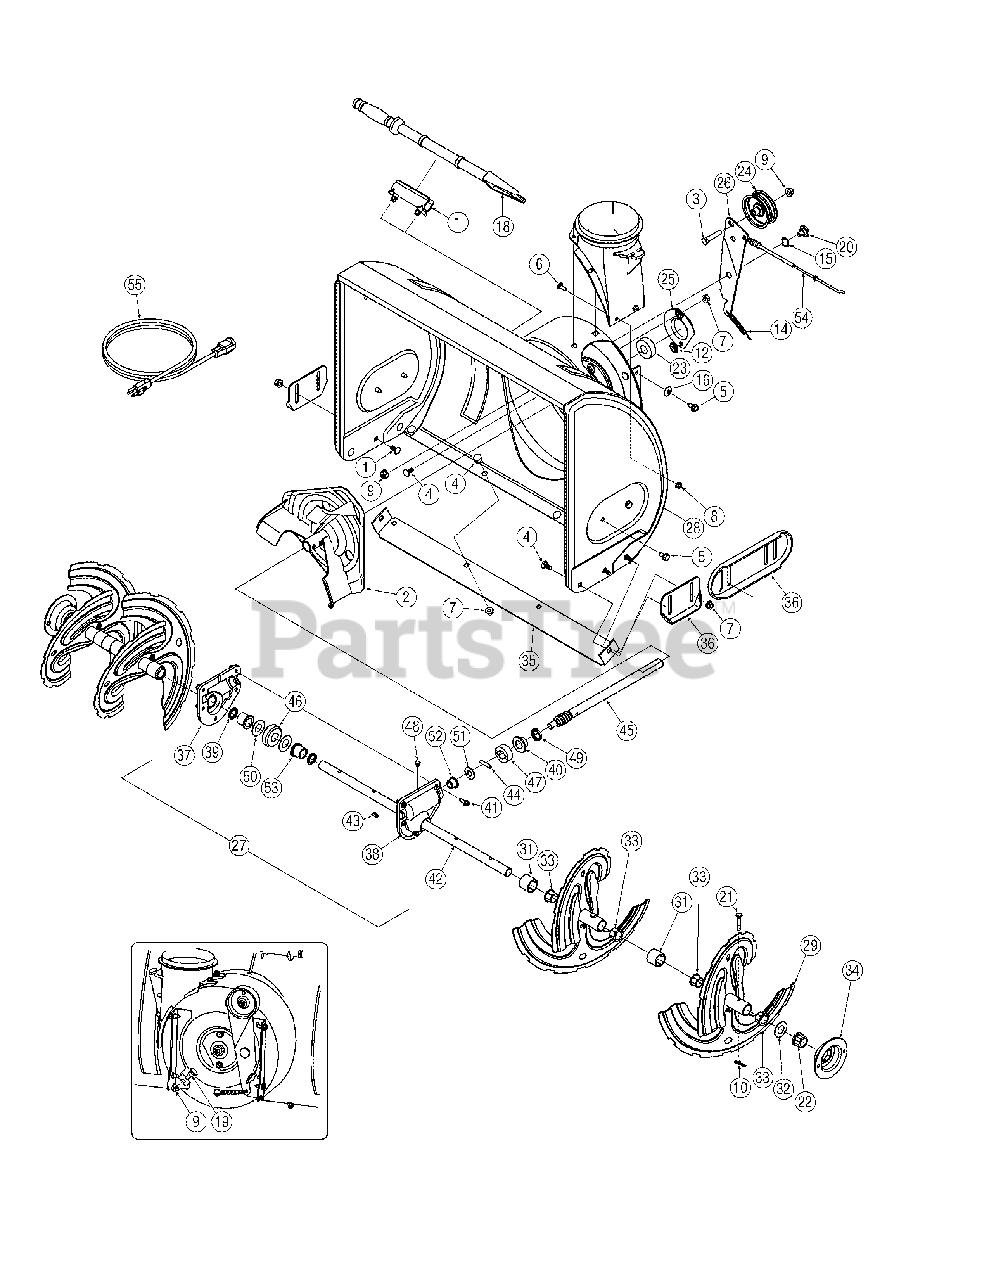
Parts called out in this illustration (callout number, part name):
1	Snow Removal Tool Mount
2	Impeller Assembly, 12" Dia.
3	Hex Screw, 3/8-16, 1.75, Gr5
4	Bolt, Carriage, 5/16-18, .750 Gr1
5	Screw, 5/16-18, 0.625
6	Screw, Carriage, 1/4-20, .750, Gr5
7	Nut, Flange Lock, 5/16-18, Nylon
8	Nut, Flange Lock, 1/4-20, Nylon
9	Nut, Flange Lock, 3/8-16, Nylon
10	Cotter Pin, Bow-tie
11	Cable, Tie, 3/16 x .05 x 7.4
12	Nut, Push-on, .25 Dia
13	Chute, Adapter 5" Dia
14	Spring, Extension, .38 OD x 3.6
15	Washer, Wave, .625 x .885 x.015
16	Washer, Bell, .340 x .872 x .060
17	Washer, Flat, .25 x .630 x .0515
18	Snow Removal Tool
19	Screw, Shoulder, .498 x .34, 3/8-16
20	Screw, Shoulder, .625 x .17, 3/8-16
21	Shear Pin, .25 x 1.50
22	Bearing, Hex Flange x .75 ID
23	Bearing, Ball, .75 ID x 1.85 OD
24	Flat Pulley, Idler, 2.75 OD
25	Housing, Bearing, 1.85 ID
27	Gearbox Assembly, Auger, 24"
31	Spacer, 1.25 OD x .75 ID -
32	Washer, Flat, .76 x 1.49 x .06
33	Bushing, Flange, .80 ID x .91 OD
40	Bearing, Flange, .75 x 1.0
41	Screw, Self-tapping, 1/4-20, 0.750
42	Axle, Auger, 24"
43	Key, Hi-pro 3/16 x 5/8
44	Pin, Dowel, .25 OD x 1.2
45	Shaft, Worm .75 OD
46	Gear, Worm 20T
47	Collar, Thrust
48	Plug, 1/4 x .437
49	Seal, Oil, .75 x 1 x .131
50	Washer, Flat, .760 ID x 1.5 OD
51	Washer, Flat, .51 x 1.12
52	Bearing, Flange, .75 x 1.0 x .925
53	Bearing, Flange, .75 x 1.00 x .975
54	Clutch Cable, Auger, 47.23"
55	Extention Cord, 110V
